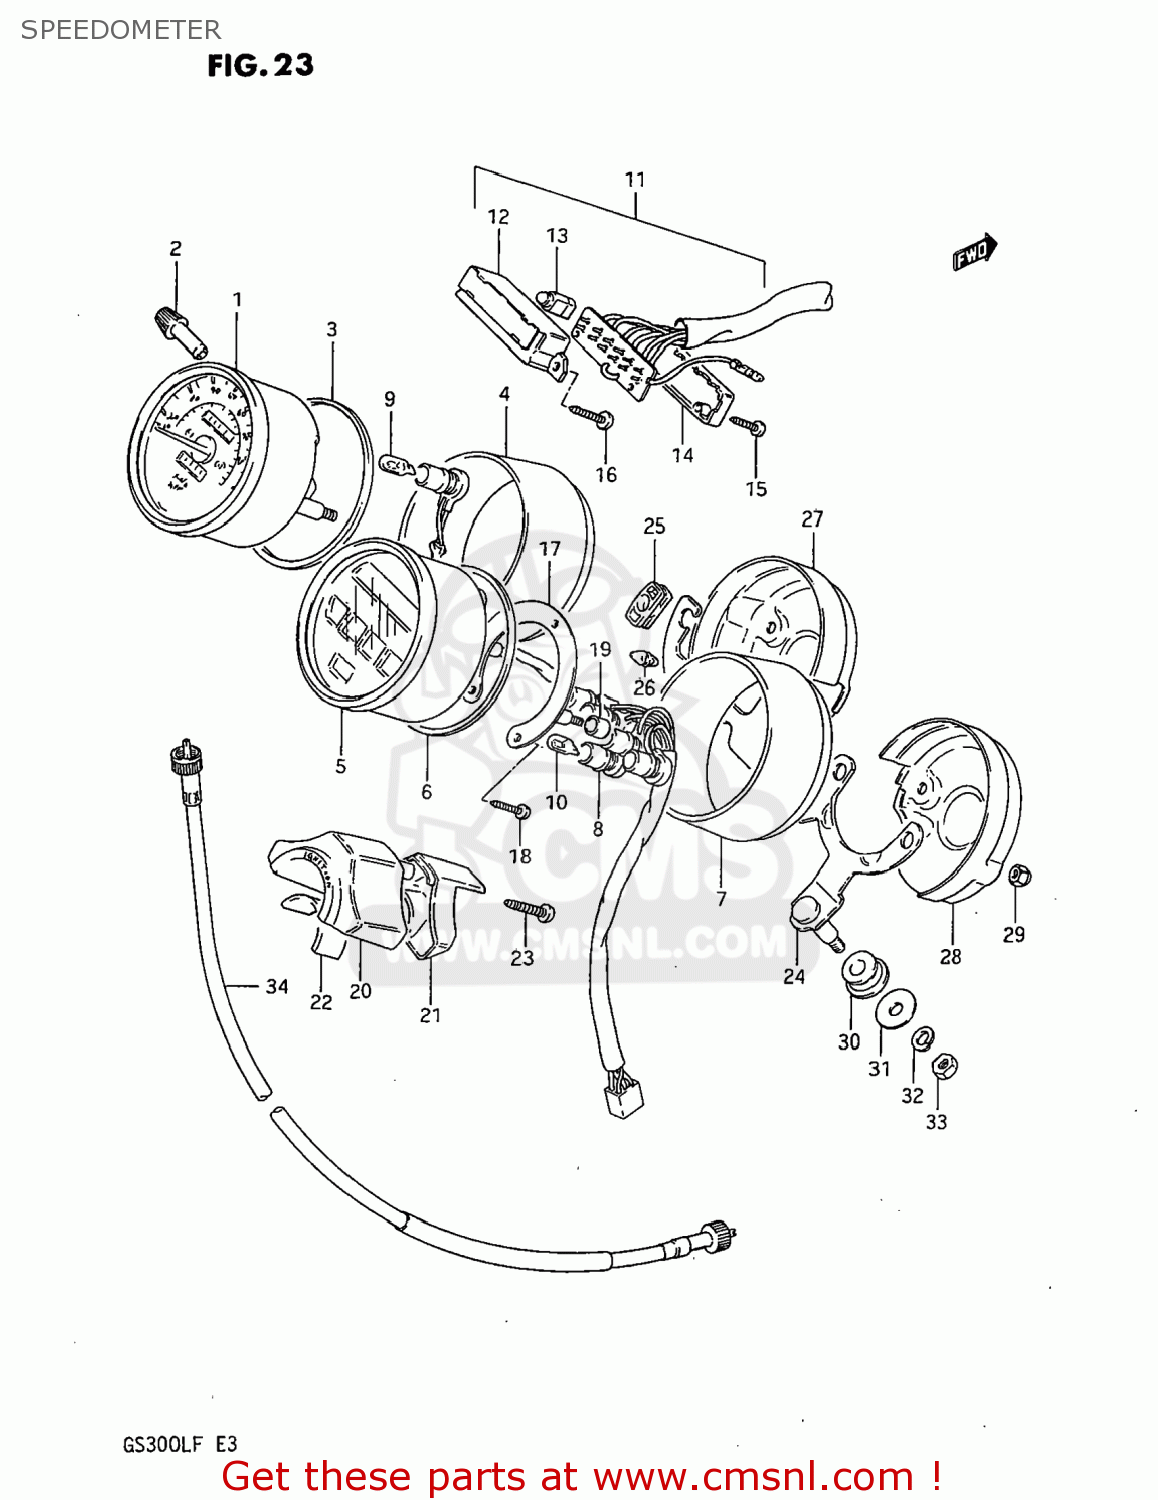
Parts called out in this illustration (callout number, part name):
1	SPEEDOMETER (MILE/KILO)
2	KNOB
3	CUSHION
4	COVER,SPEEDOMETER
5	BOX ASSEMBLY,PILOT LAMP
6	CUSHION
7	COVER,TACHOMETER
8	SOCKET
9	BULB(12V1.7W,T10,WB121)
10	BULB(12V3.4W,T10)
11	INDICATOR ASSEMBLY,GEAR POSITION
12	CASE,GEAR INDICATOR
13	BULB(14V1.12W,BQ041-32503B)
14	COVER,LWR
15	SCREW,GEAR INDICATOR
16	SCREW,INDICATOR
17	CUSHION,METER
18	SCREW
19	CAP
21	COVER,IGNITION SWITCH
22	SEAL,IGNITION SWITCH
24	BRACKET,METER
25	CUSHION,METER
26	CUSHION
27	ORNAMENT,SPEEDOMETER
28	COVER,INDICATOR,UNDER
29	NUT
30	CUSHION,METER BRACKET
31	WASHER (8.5X20X1.6)
32	WASHER,LOCK,8.
33	NUT
34	CABLE ASSEMBLY,SPEEDOMETER
